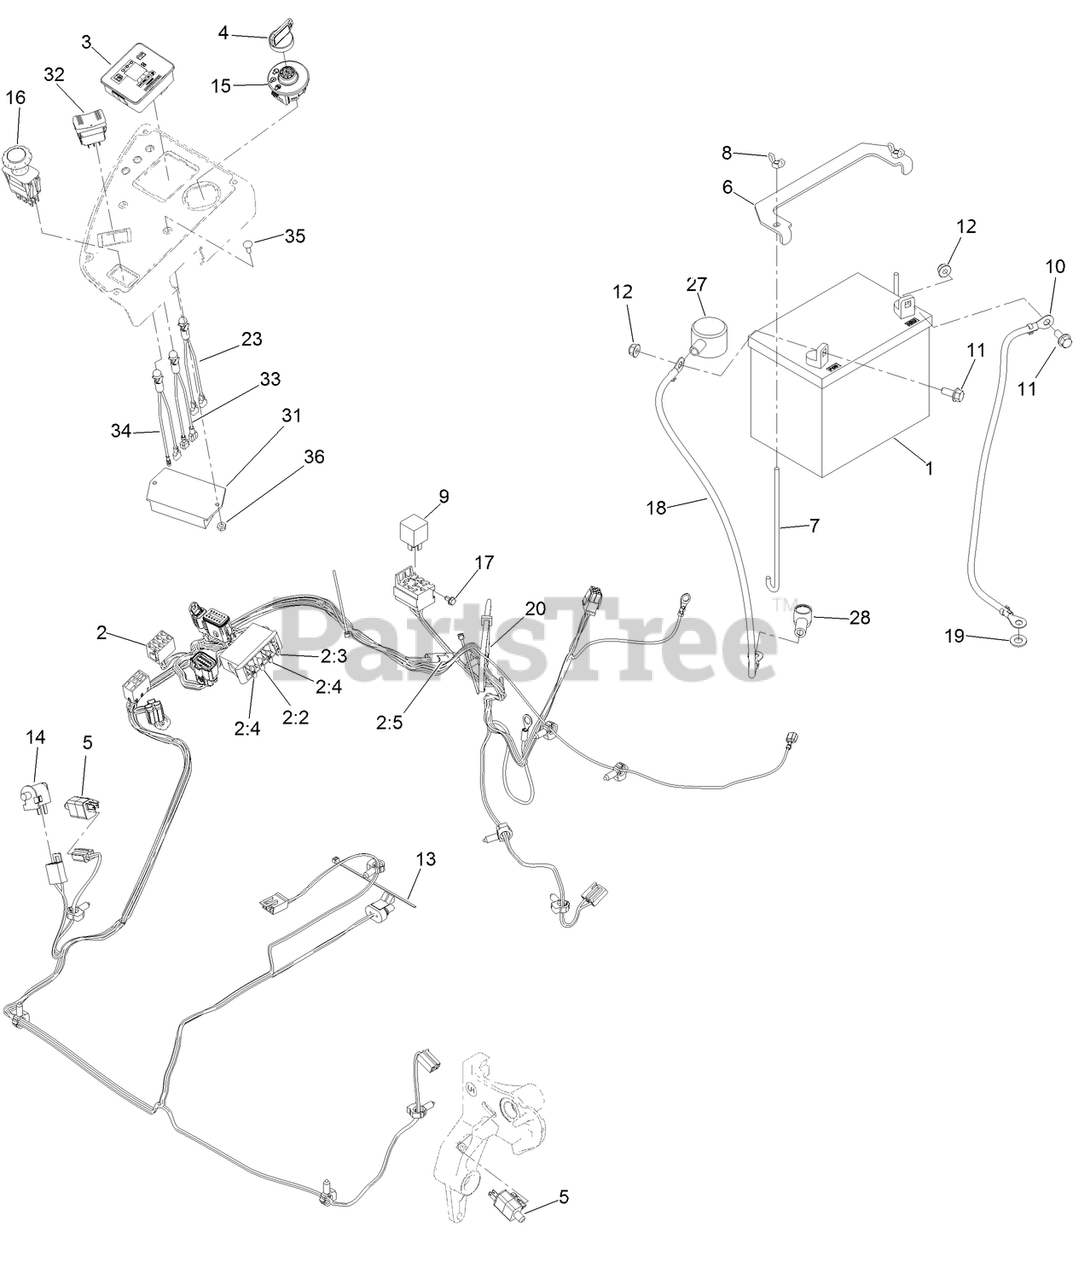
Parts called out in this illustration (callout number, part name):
1	BATTERY (340 CCA, WET)
2	HARNESS-WIRE
2:2	FUSE-BLADE, 10 AMP
2:3	FUSE-BLADE, 15 AMP
2:4	FUSE-BLADE, 25 AMP
2:5	CAP-PLUG
3	FUEL/HOUR METER ASM
4	KEY-IGNITION
5	SWITCH
6	STRAP-TIE DOWN, BATTERY
7	BOLT-HOLDDOWN
8	WINGNUT
10	CABLE-BATTERY, NEGATIVE
11	SCREW-HHF
12	NUT-HF, NI
13	TIE-CABLE
14	SWITCH-BAIL
15	SWITCH-IGNITION
16	SWITCH-PTO, 10 AMP
17	SCREW-HWH
18	CABLE-BATTERY, POSITIVE
19	WASHER-FLAT
20	TIE-PLASTIC
23	INDICATOR-LED, RED
27	INSULATOR-BATTERY
28	INSULATOR-SOLENOID
31	CONTROLLER-RED
32	SWITCH-ROCKER
33	LIGHT-LED, RED
34	LIGHT-LED, RED
35	SCREW-CARR
36	NUT-LOCK, NI
